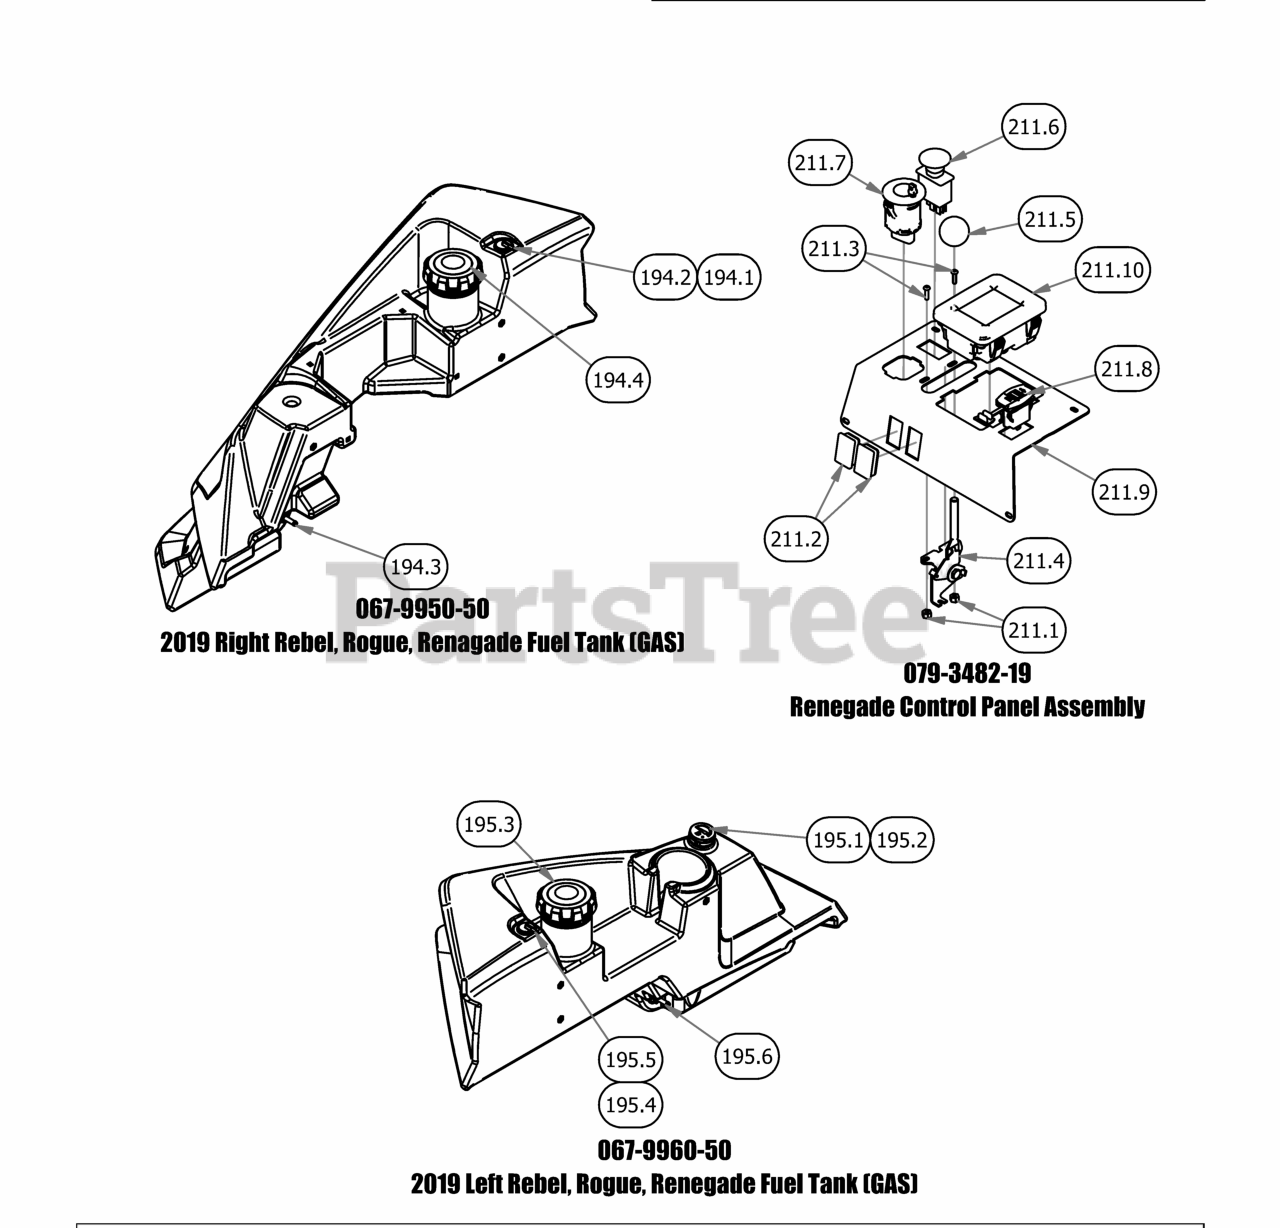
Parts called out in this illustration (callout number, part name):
194.1	Roll Over Valve Grommet
194.2	Rollover Valve
194.3	Fuel Pick-up
195.1	Fuel Gauge with Grommet
195.2	Fuel Gauge Grommet
195.4	Roll Over Valve Grommet
195.5	Rollover Valve
195.6	Fuel Pick-up
211.1	10-24 Nylon Insert Locknut
211.2	Light Plug
211.3	10-24 X 5/8 BS Button Head Bolt
211.4	Universal Throttle
211.5	Throttle Knob
211.6	PTO Switch
211.7	2019 Push to Start Switch w/fob
211.9	2019 Outlaw Digital Control Panel
211.10	2019 LED Display
